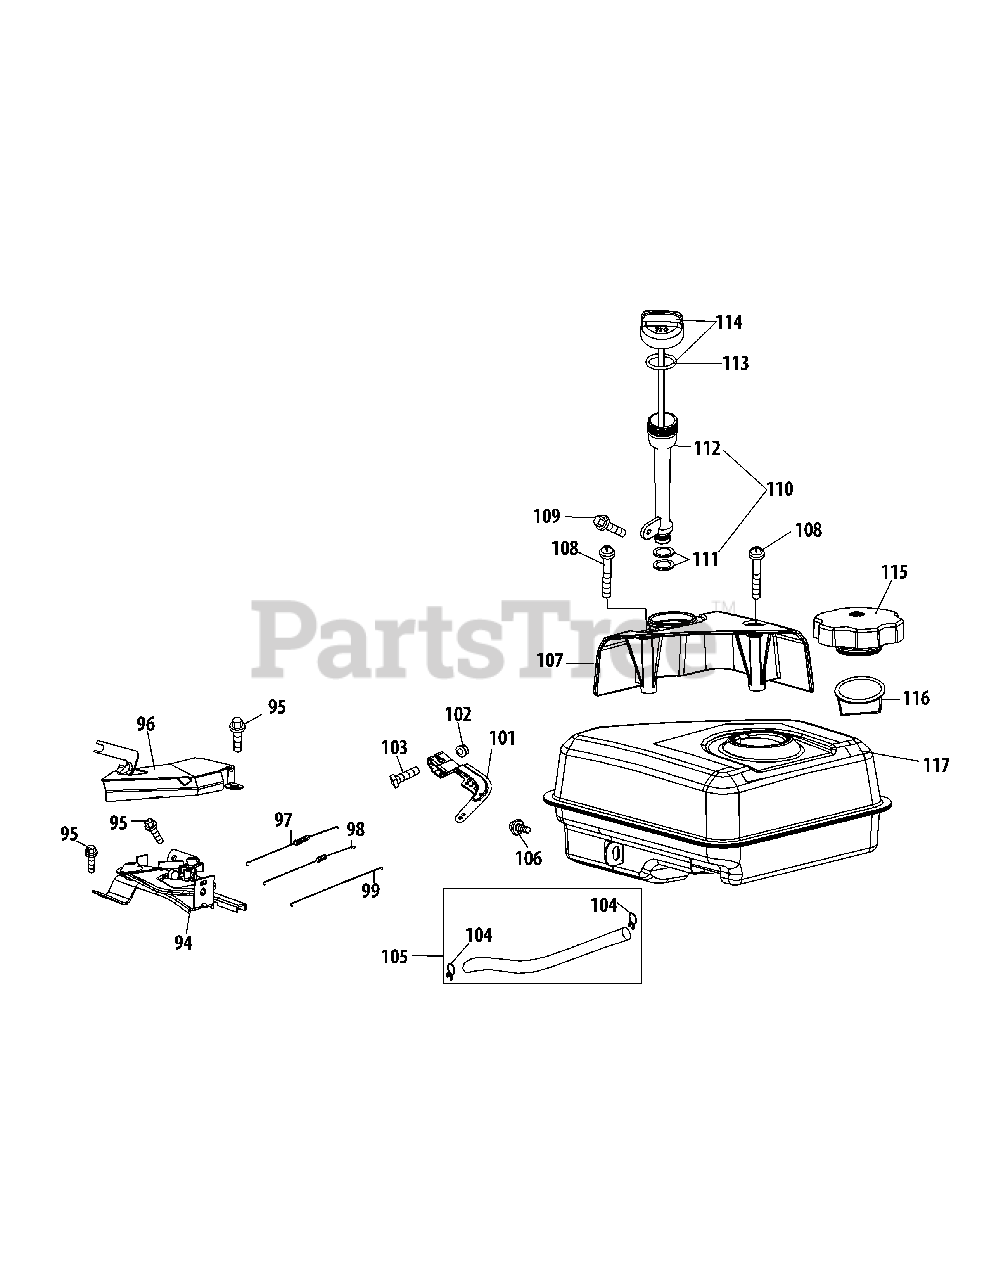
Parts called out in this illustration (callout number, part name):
94	Throttle Control Assembly
95	Bolt-M6 X 12
96	Shield - Governor
97	Governor Spring
98	Spring-Throttle Return
99	Rod-Governor
101	Bracket - Governor
102	Nut - M6
103	Bolt - M6 X 21 Gov
104	Hose Clamp-Carb
105	Kit-Fuel Line
106	Bolt - M6 X 12 Zin
107	Engine/Dipstick Cover
109	Bolt - M6 X 12 Zin
110	Oil Fill Tube Assembly
112	Dipstick Tube
113	O-Ring Dipstick
114	Dipstick Assy
116	Fuel Level Indicator
